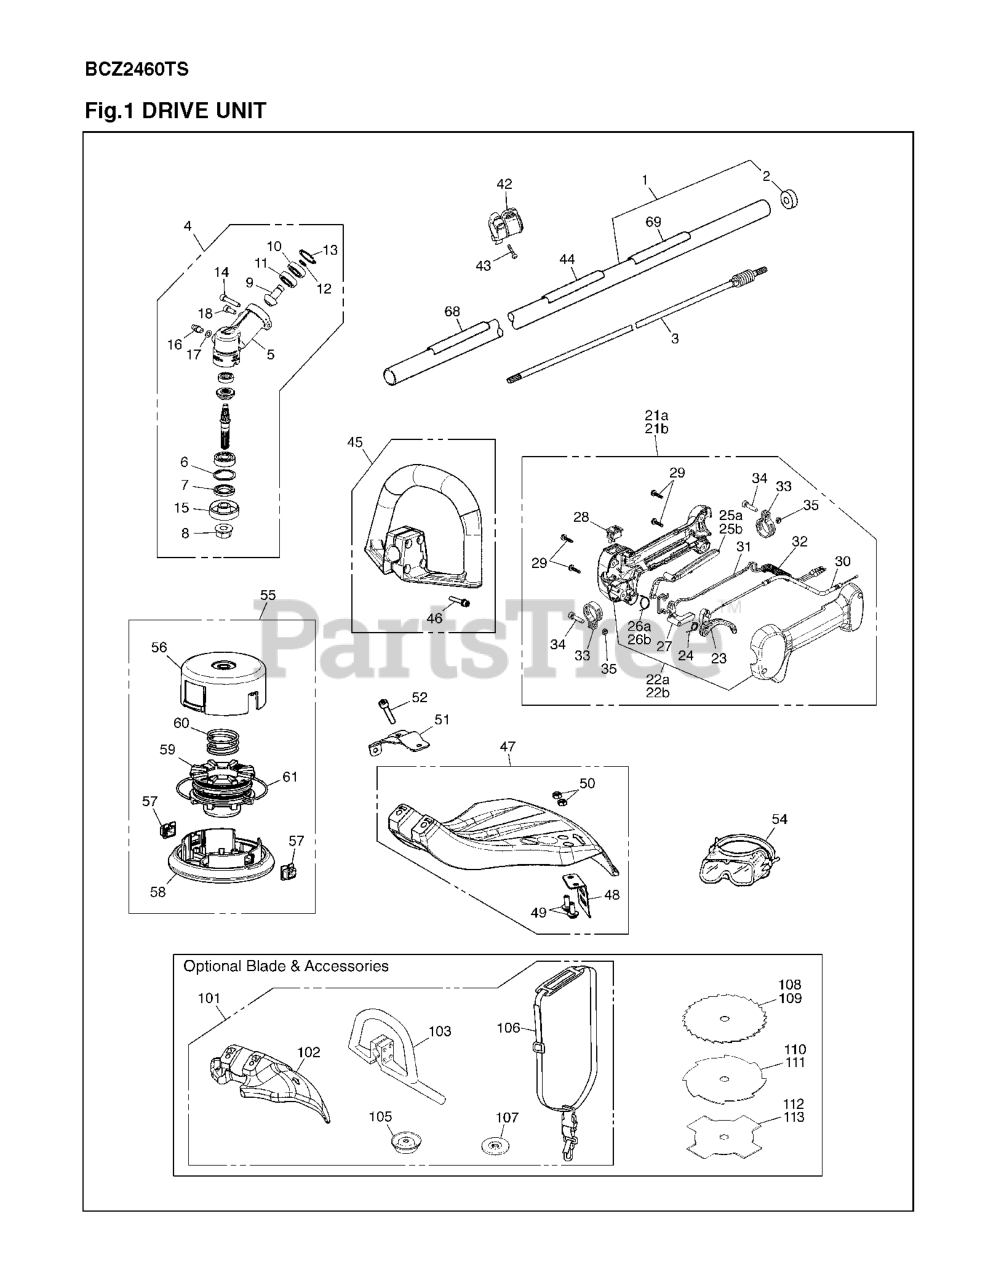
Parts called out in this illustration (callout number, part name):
1	PIPE COMP
3	DRIVESHAFT
4	GEARCASE ASSY
5	GEARCASE
6	RING,SNAP M26x1.2 RP-318013340
11	BALL BEARING
14	BOLT TORX
15	HOLDER(A)
18	BOLT, TORX
21	GRIP ASSY
22	GRIP HALF SET
23	LEVER, THROTTLE
24	SPRING, THROTTLE
25	LEVER FOR GRIP (RPLS -0600)
25	LEVER, SAFETY
26	SPRING JOINT
26	SPRING
27	LEVER JOINT
31	CORD - C
35	NUT
42	HANGER COMP.
44	LABEL CAUTON FOR BC
45	HANDLE ASSY. (RPLS T319514001)
47	GUARD ASSY
52	BOLT, TORX
54	GOGGLExxx (RPLS
55	4" TAP TRIMMER HEAD PT104
56	CASE (RPL T318915112)
58	COVER (RPLS T318915131)
59	HOLDER, CORD (RPLS T318915141)
61	CORD
69	NAME PLATE BCZ260TS
101	BLADE KIT FOR BCZ2460
103	HANDLE-ASSY
106	STRAP ASSY
107	HOLDER (B)
108	Brushcutter Blade, 22 Tooth 9"
109	Brushcutter Blade, 24 Tooth 9"
110	BLADE, 8
111	Brushcutter Blade, 8 Tooth 9"
112	BLADE, 8
113	Brushcutter Blade, 4 Tooth 9"
